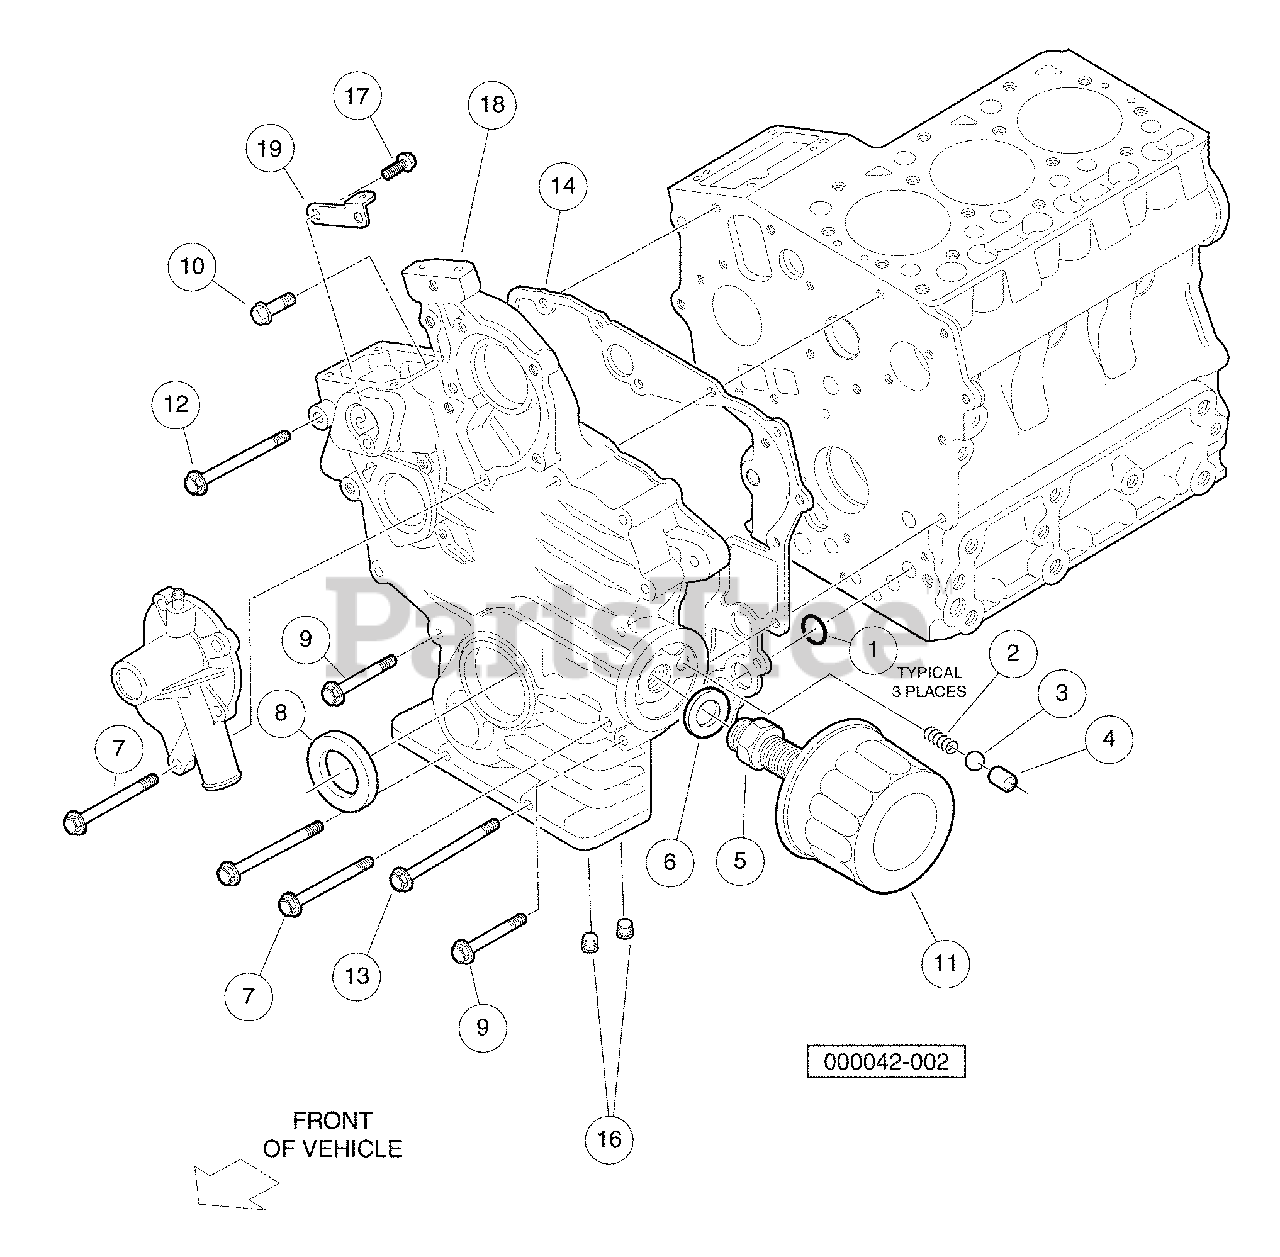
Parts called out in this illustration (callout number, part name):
1	O Ring, 18 X 13
2	Spring, Valve
3	Ball, Valve
4	Seat, Valve
5	Joint, Pipe
6	Washer, Plain, Special
7	Bolt, M6 X 1 X 60
9	Bolt, D722, Front Case
10	Bolt, D722 Intake Manfld Lower
11	Filter, Engine Oil, D722
12	Bolt, Gearcase, Top
13	Bolt, Gearcase, Lower
14	Gasket, Gearcase, D722
15	Case, Gear
16	Plug, 1/4"
17	Screw, Breather
18	Case, Gear
19	Stay, Spring
